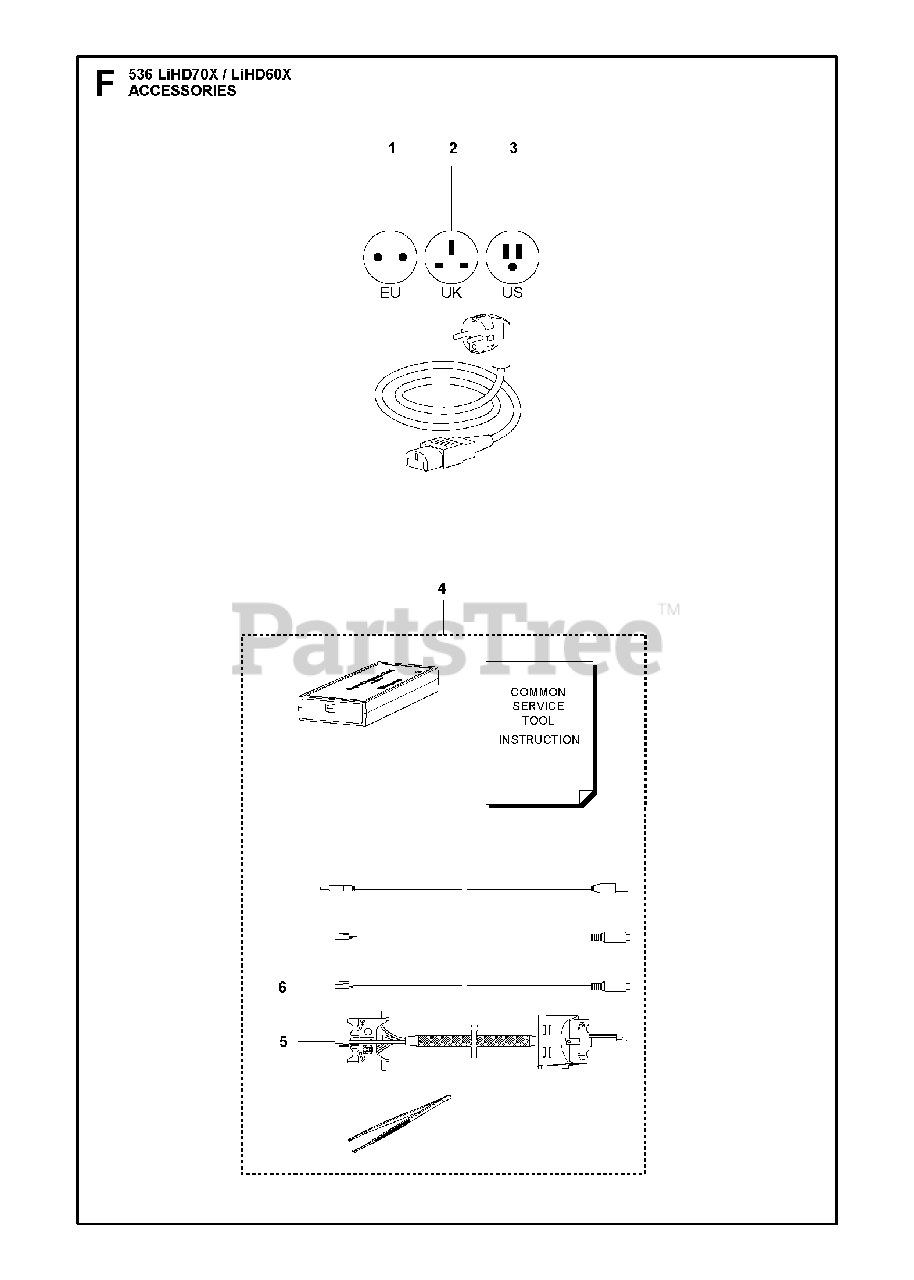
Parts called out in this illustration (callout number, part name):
1	MAIN CABLE
4	DIAGNOSTIC TOOL KIT
5	WIRING ASSY
6	CABLE ASSY
